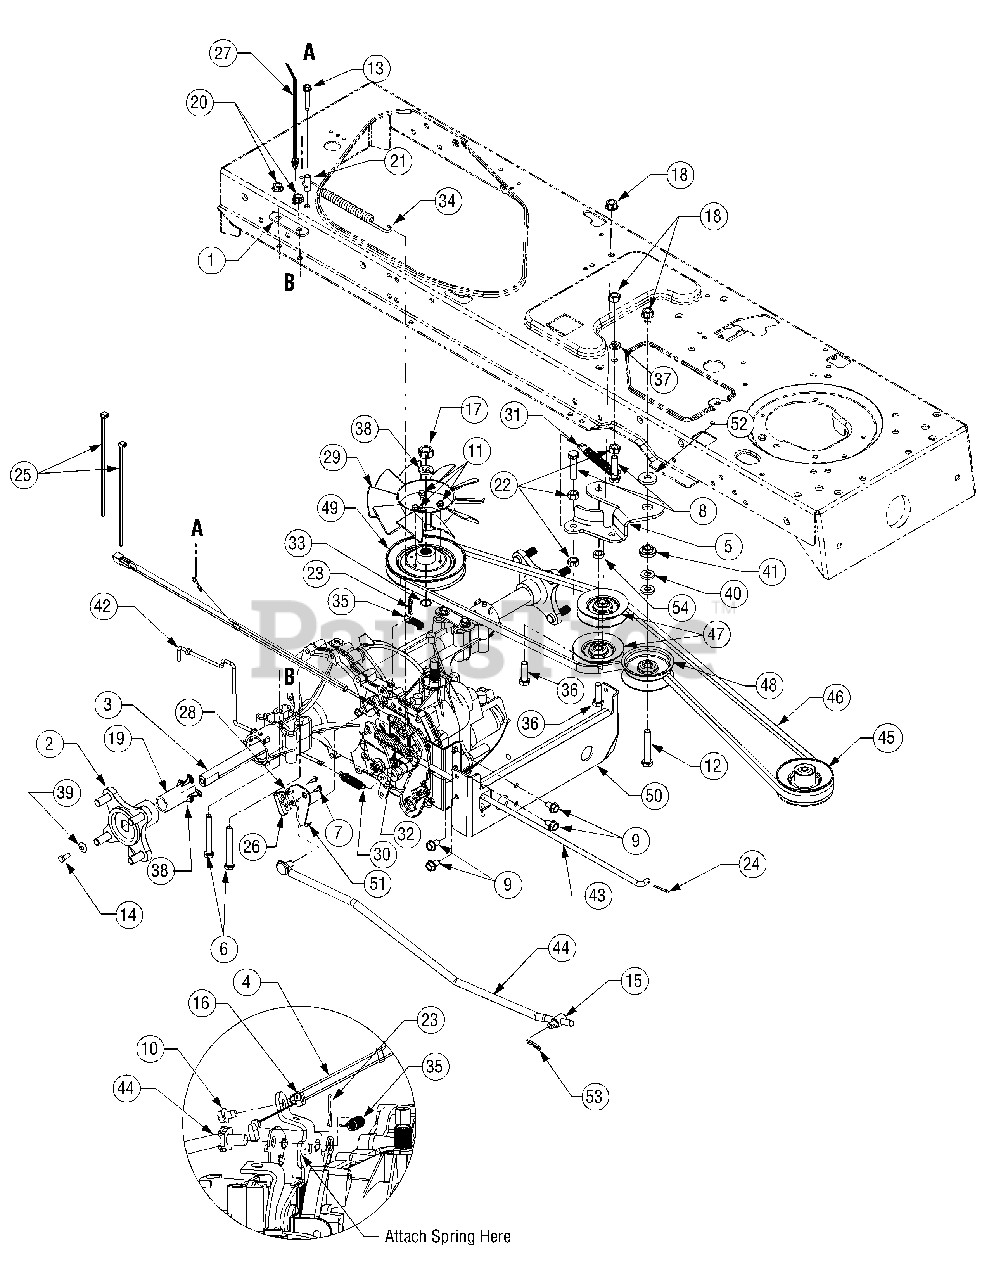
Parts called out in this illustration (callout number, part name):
1	Bracket, Mounting, Transaxle
2	Hub Assembly, Wheel
3	Transmission, Hydrostatic
4	Harness Assembly, Ground & Reverse
6	Hex Cap Screw, 5/16-18,3.5, Gr5
7	Screw, #8-18, 0.500
8	Hex Cap Screw, 3/8-16, 1.50, Gr5
9	Screw, 5/16-12, 0.75
10	Screw, 1/4-20, 0.5
11	Screw, #12-24, 0.375
12	Hex Cap Screw, 3/8-16, 2.25, Gr5
13	Hex Cap Screw, 1/4-20, 1.5, Gr5
14	Hex Cap Screw, 5/16-24 x .750
15	Ferrule, 3/8-24 x .375 Dia
16	Nut, Hex Lock, 1/4-20
17	Nut, Hex, 1/2-20, Gr5
18	Nut, Nylon Lock, 3/8-16
19	Sleeve, 2.4"
20	Nut, Nylon Lock, 5/16-18, Gr5
21	Spacer, 1"
22	Nut, Hex, 3/8-16, Gr8
23	Pin, Cotter, .072 Dia. x 1.13 Lg
24	Pin, Cotter, 3/32, 1.0
25	Cable, Tie, 3/16 x .05 x 7.4
26	Switch, Spring, Short
27	Tie, Cable, Push Mount 7.5 Lg
28	Plate, Insulator Nut
29	Fan, Blade, 10"
30	Spring, .48 OD x 2.03 Extension
31	Spring, Extension, .563 Dia x 3.72 Lg
32	Spring, Extension, .59 OD x 4.00 Lg
33	Ring, Wire
34	Spring, Extension, .500 Dia x 7.0
35	Spring, Extension, 3/8 OD x 1.44
36	Screw, 3/8-16, 1.25
37	Washer, Lock, 3/8, Regular Duty
38	Washer, Lock, 1/2
39	Bell Washer
40	Washer, Flat, .407 x .812 x .135
41	Spacer, Shoulder, 1.00 x .38 x .38
42	Rod, Hydro Bypass
43	Rod, Brake, Hydro
44	Rod, Control, Hydro
45	Pulley, Engine, 3.56 Dia.
46	Belt, V Type, Poly
47	Pulley, Idler, V Type x 3.06 Dia
48	Pulley, Idler, Flat 2.75 OD
49	Pulley, Engine, 4.11Dia.
50	Bracket, Transmission, Torque Hydro
51	Bracket, Actuator, Switch
52	Washer, Flat, .38 x 1.92 x .060
53	Pin, Cotter, 3/32, .750
54	Spacer, .38 x .625 x .21
